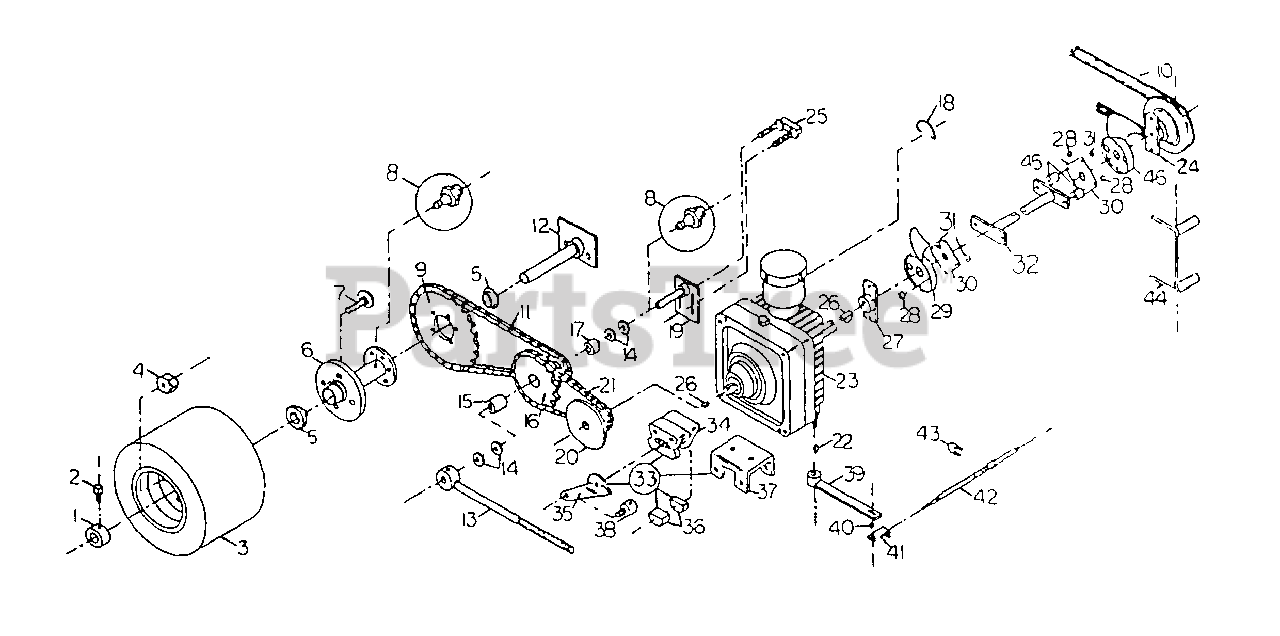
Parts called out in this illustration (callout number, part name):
1	Set Collar, 1"
2	Squarehead Setscrew, 5/16 - 18 x 1/2"
3	Drive Wheel Ass'y., 16 x 7.50-8
4	Lug Nut, 1/2-20
5	Drive Wheel Bearing
6	HUB - drive wheel
7	Lug Bolt, 1/2-20 x 1 1/4"
8	Self - tapping Zerk, 1/4-28
9	Final Drive Sprocket, 40A 54
10	Transmission Belt
11	CHAIN - final drive
12	Drive Wheel Axle
13	Support Collar
14	Machine Washer, 3/4", 10 GA.
15	Idler Sprocket Bearing, 1/2"
16	Idler Sprocket
17	Idler Sprocket Bearing, 3/4"
18	Transmission Dump Valve Clip
19	Idler Sprocket Shaft
20	Transmission Sprocket w/Brake disc
21	CHAIN - primary drive
22	Woodruff Key, 1/8" x 3/8"
23	Transmission, L.H.
24	Pulley w/Drive Plate
26	Woodruff Key, 1/8" x 1/2"
27	Hub w/Drive Plate
30	Drive Plate
31	Washer, 1/4", 10 GA.
33	Brake Assembly, L.H.
34	Brake Caliper
35	Caliper Lever, L.H.
36	Brake Pad (Set)
37	Caliper Bracket
38	Caliper Rod Collar
39	Transmission arm, L.H.
40	Cable End Bushing
41	Steering Cable End
42	Steering Cable
43	Steering Cable Clamp
44	Transmission Belt Retainer
